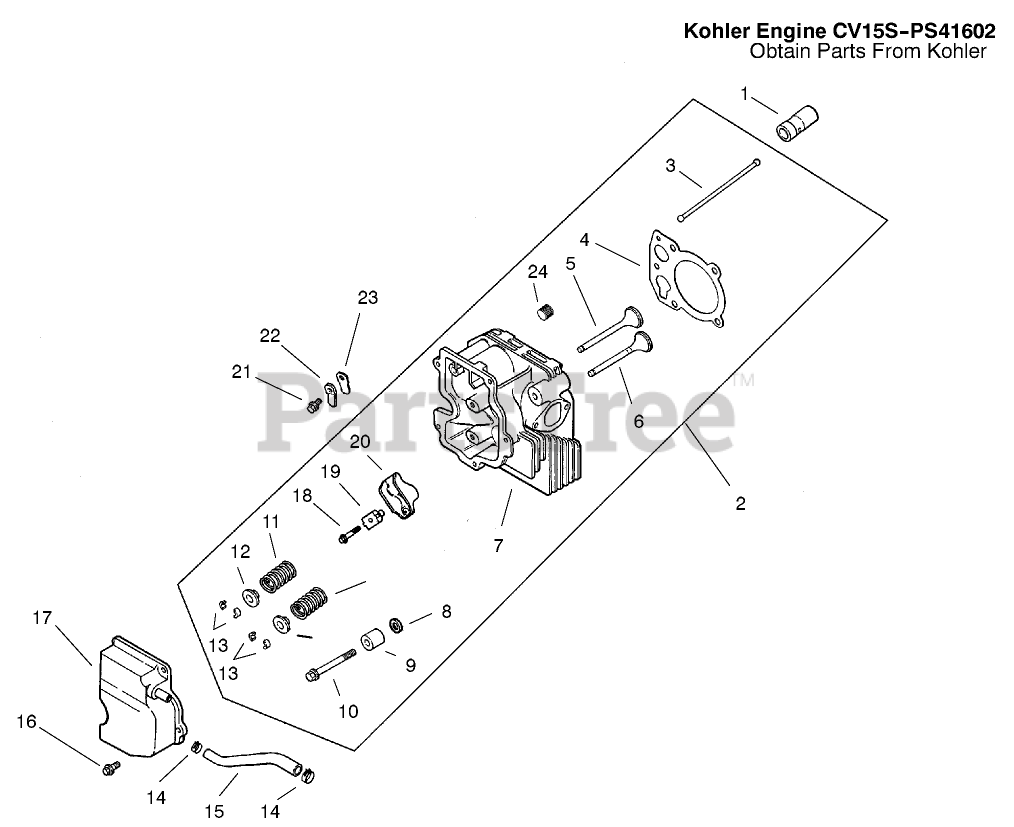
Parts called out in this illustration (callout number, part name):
1	Lifter-Valve
2	gasket)
3	Rod-Push (Only On: 72042,72043,72062,72063)
4	Gasket-Cylinder Head
5	Valve-Intake STD (Only On: 72042, 72063, 72062, 72043)
6	Valve-Exhaust STD (Only On: 72042,72043,72062,72063)
7	Head-Cylinder
8	Washer-Flat (Only On: 72042, 72063, 72062, 72043)
9	Spacer-Head Bolt Exhaust (Only On: 72042, 72063, 72062, 72043)
10	Screw M10x1.5x80 (Only On: 72042, 72063, 72062, 72043)
11	Spring-Valve Intake (Only On: 72042, 72063, 72062, 72043)
12	Cap-Valve Spring
13	Kit-Retainer
14	Clamp-Hose
15	Hose-Breather (Only On: 72042, 72063, 72062, 72043)
16	Screw-HF (M6x1.0x20)
17	Cover-Valve W/Nipple (Only On: 72042, 72063, 72062, 72043)
18	Screw-HF (M6x1.0x34)
19	Pivot-Rocker Arm
20	Arm-Rocker
21	Screw (M5x0.8x10)
22	Retainer-Reed
23	Reed-Breather
